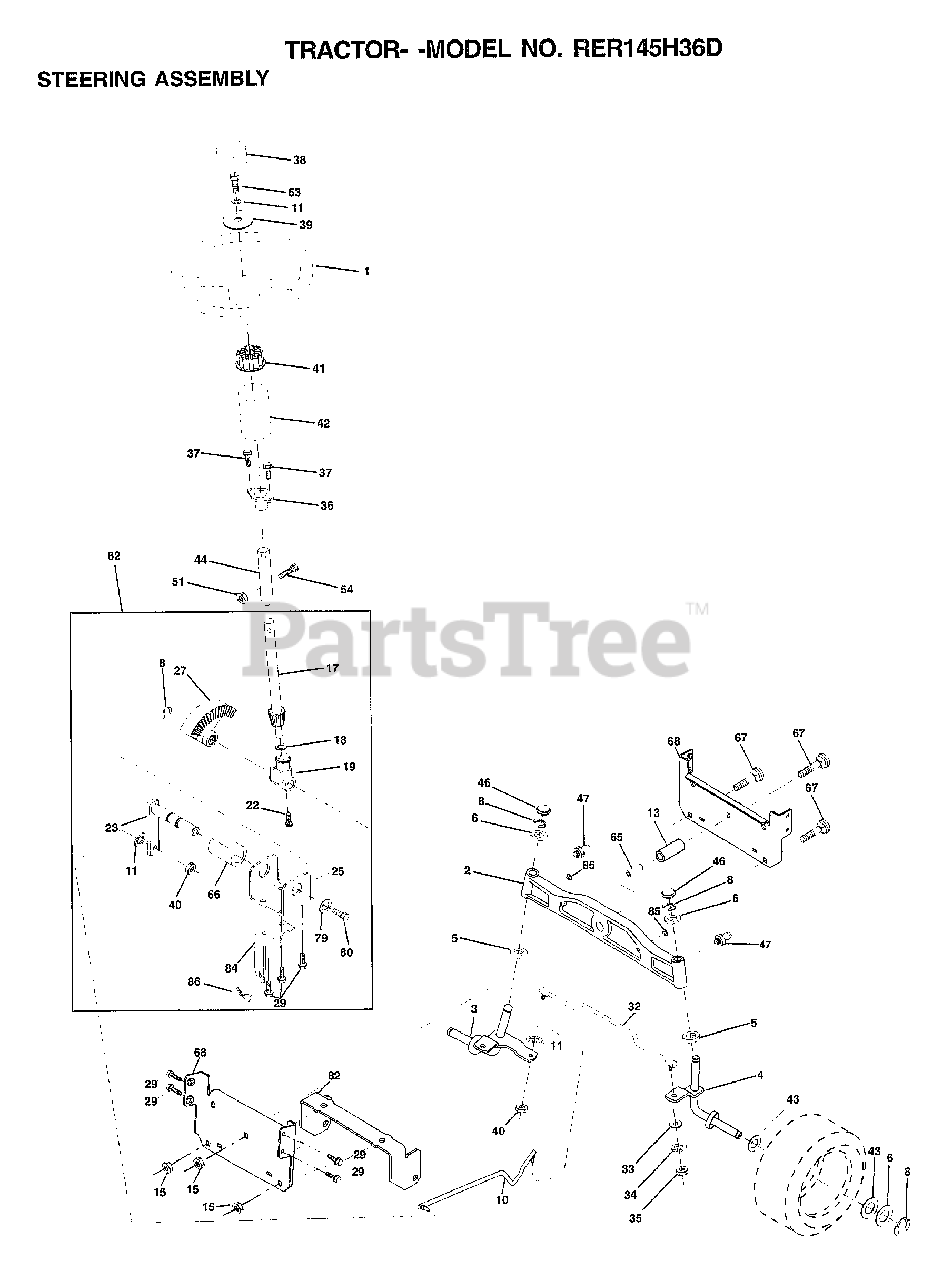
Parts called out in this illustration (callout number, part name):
2	AXLE ASSY
3	SPINDLE ASM
4	SPINDLE ASM
5	WASHER .T
6	WASHER
8	RING
10	LINK DRAG
11	LOCKWASHER
13	SPACER BEARING
15	NUT.HXFLG.LOCK.
17	SHAFT ASM STEERIN
18	THRUST WASHER
19	SUPPORT.SHAFT.STEER
22	SCREW.HX.WSH.HD
23	SHAFT.ASM.PITMAN
25	BRKT-STEERING
27	GEAR SECTOR
29	SCREW
32	TIE ROD
33	WASHER M
34	LOCKWASHER
35	NUT.LOCK.5/16-24
36	BUSHING.STEERING
37	"SCREW-TT,10-32 FL"
38	ST WHL INSERT CAP
39	WASHER
40	GRIPCO NUT
41	ADAPTER LT
42	BOOT.STEERING.DASH.P/L
43	WASHER
44	EXT SHAFT STEERIN
46	CAP
47	ZERK M
51	NUT
54	BOLT
62	KIT.STEER.ASM
63	BOLT
65	"SPACER BRCAE,AXLE"
66	"BEARING-ARM,PITMA"
67	BOLT RDHD 3/8-16
68	BRACE AXLE
79	WASHER
80	BOLT.HX.NYLON3/8-16X3/
82	BRKT SUSP CHASSIS FRT
84	BRACKET CABLE CLUTCH CHASSIS
85	XMAS TREE FASTNER
86	RETAINER SPRING
